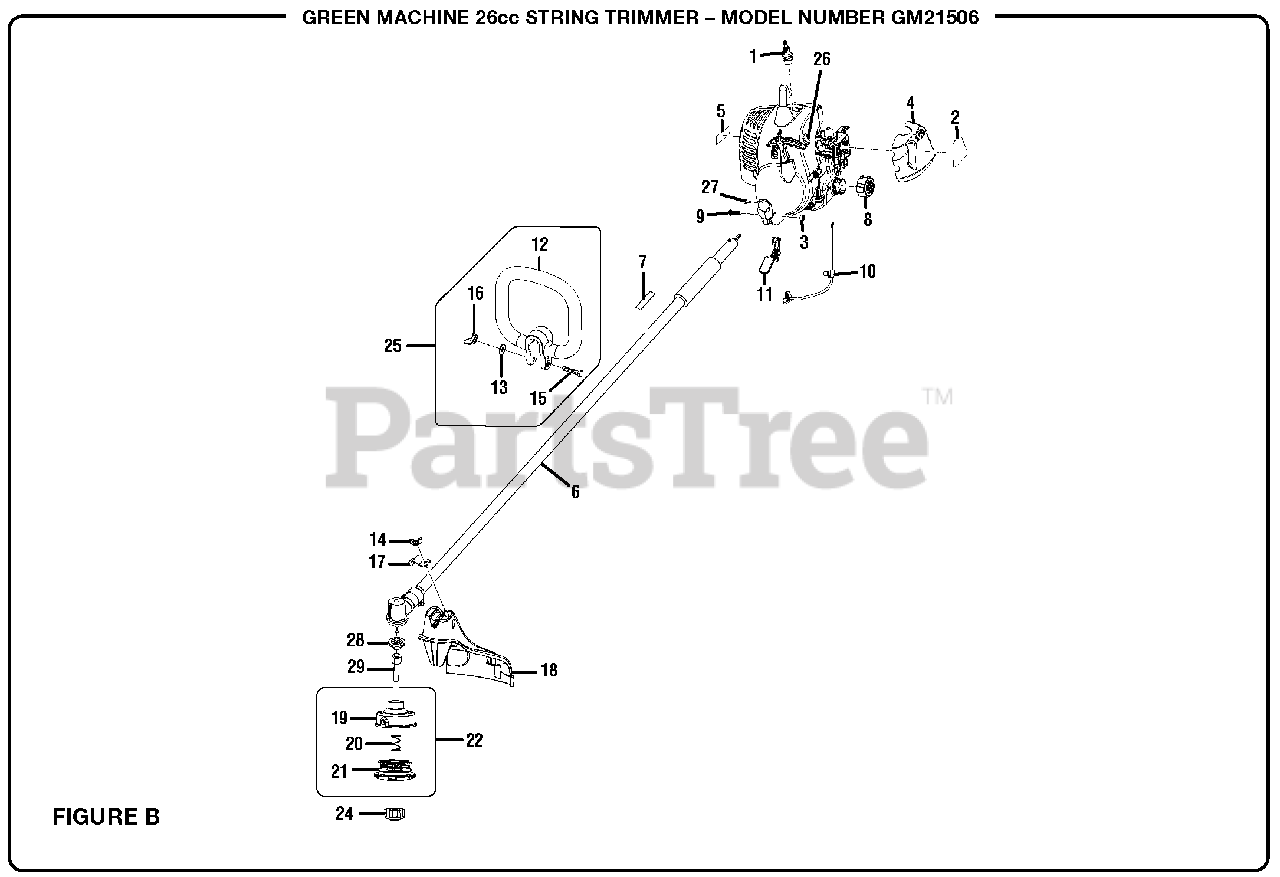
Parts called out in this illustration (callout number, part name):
1	Spark Plug (Champion RCJ6Y)
2	Starting Label
3	Hex Nut (M6)
4	Airbox Cover
5	Combustion Warning Label
6	Boom Assembly
7	Warning Label
9	Bolt (M6 x 20 mm)
10	Throttle Cable
11	Throttle Trigger
14	Wing Nut (1/4-20)
15	Bolt (1/4-20 x 40 mm)
16	Wing Nut (1/4-20)
17	Mounting Bracket
18	Straight Shaft Grass Deflector
19	String Head Housing
20	Spool
21	Spring
22	String Head Assembly
24	Spool Retainer
25	Handle Assembly
26	Switch
27	Screw (8-16 x 5/16 in)
28	Flange Washer
29	Shaft Adapter
